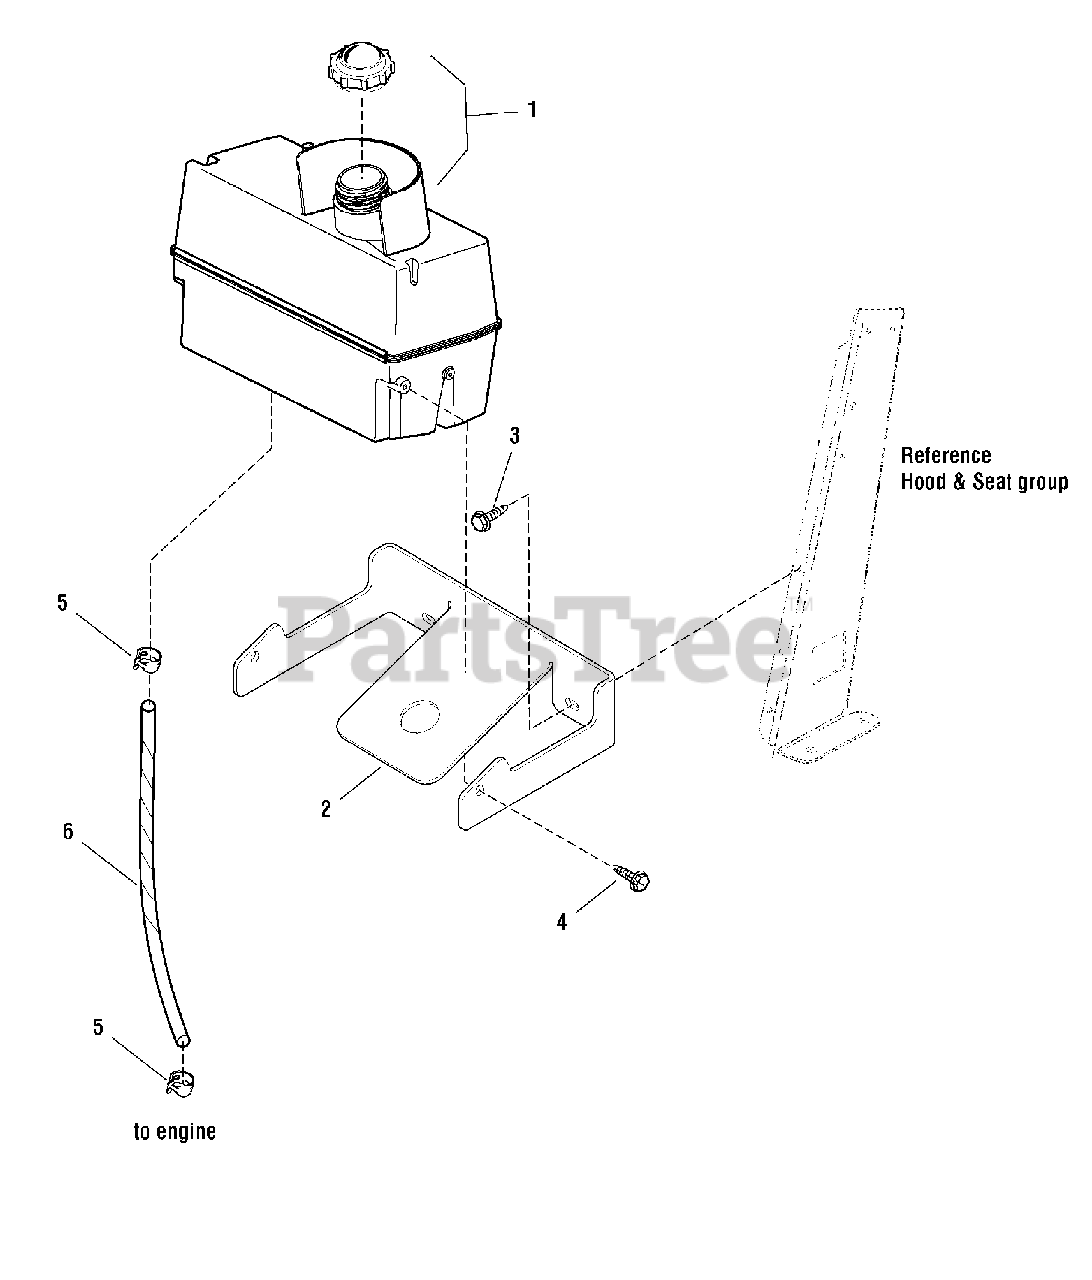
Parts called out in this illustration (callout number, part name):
1	FUEL TANK, w/ Cap
2	BRACKET, Tank
3	SCREW, 1/4-20 x 1/2
4	SCREW, Self Tap, 1/4-20 X 5/8
5	HOSE CLAMP
6	HOSE, Fuel, Low Perm 17 in
